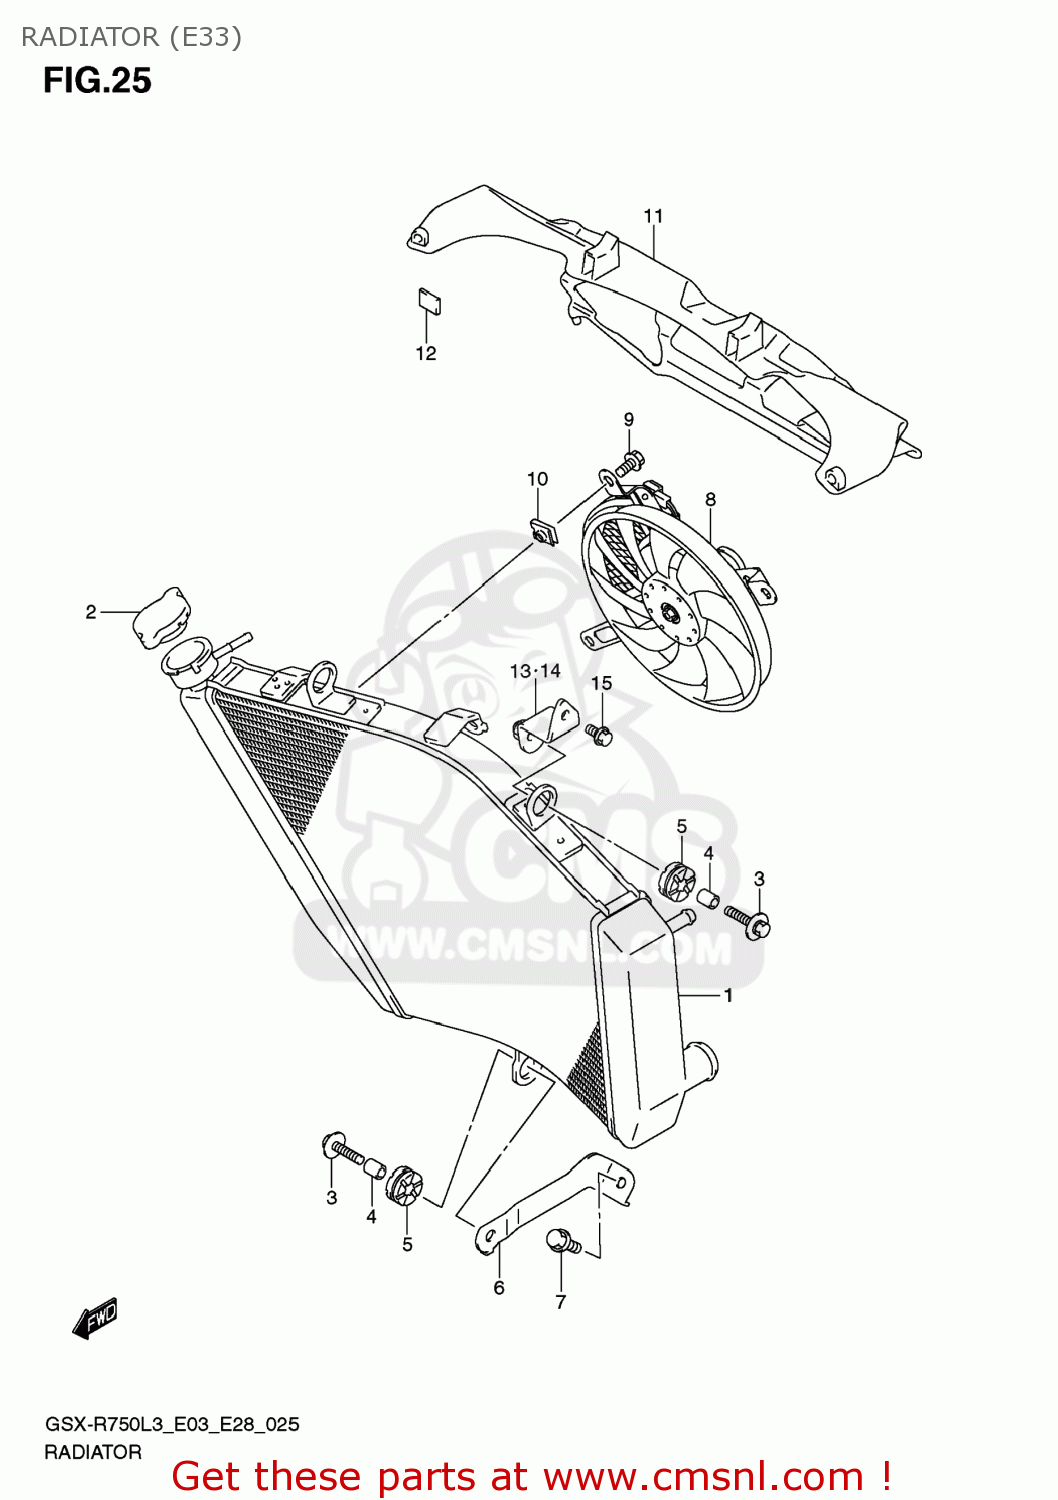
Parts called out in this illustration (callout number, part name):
1	RADIATOR ASSY,WATER
2	CAP,RADIATOR(1.1)
3	BOLT(6X25)
4	SPACER(6.5X10X12)
5	CUSHION
6	BRACKET,RADIATOR
7	BOLT
8	FAN ASSY,RADIATOR
9	BOLT,FAN ASSY
10	NUT,RADIATOR FAN
11	SHIELD,RADIATOR HEAT
12	PAD
13	BRACKET,RADIATOR UPR,R
14	BRACKET,RADIATOR UPR,L
15	BOLT
